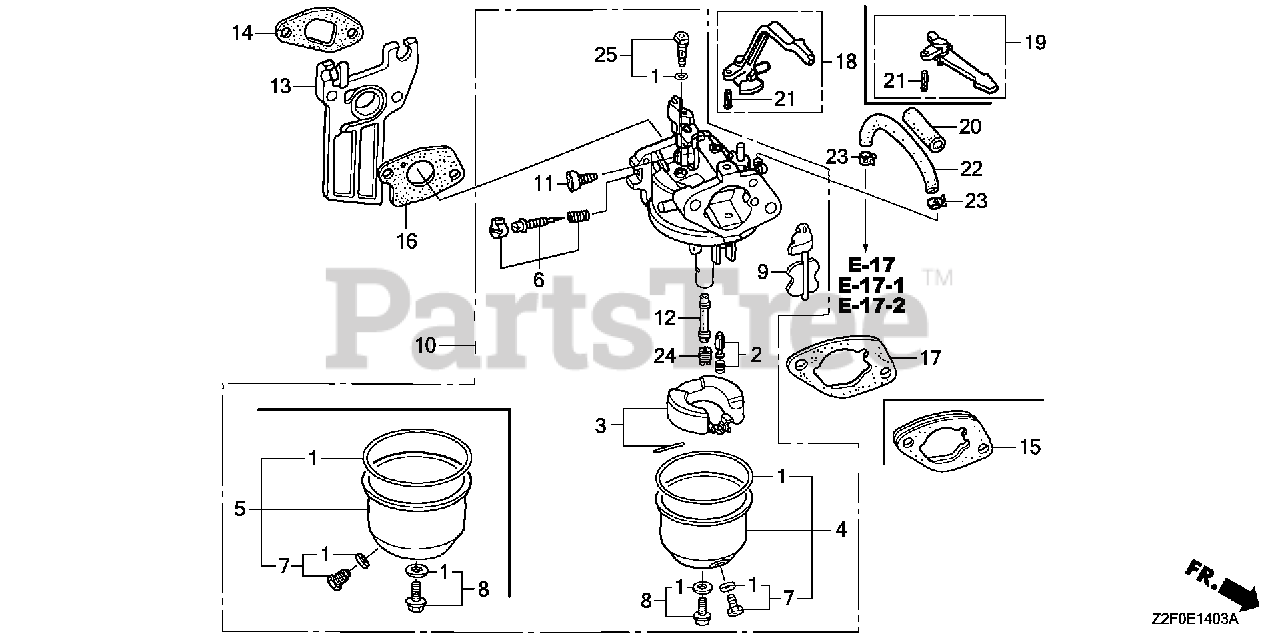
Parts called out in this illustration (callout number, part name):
1	GASKET SET
2	VALVE SET, FLOAT (SEAT NOT INCLUDED)
4	CHAMBER SET, FLOAT
6	SCREW SET, PILOT
7	SCREW SET, DRAIN
8	SCREW SET
10	CARBURETOR ASSY. (BE67A B)
11	SCREW, THROTTLE STOP
12	NOZZLE, MAIN
13	INSULATOR, CARBURETOR
14	GASKET, INSULATOR
16	GASKET, CARBURETOR
17	GASKET, AIR CLEANER
18	LEVER, CHOKE
21	PIN, SPRING (2X12)
24	JET, MAIN (#72)
24	JET, MAIN (#75)
24	JET, MAIN (#70)
25	JET SET, PILOT (#35)
